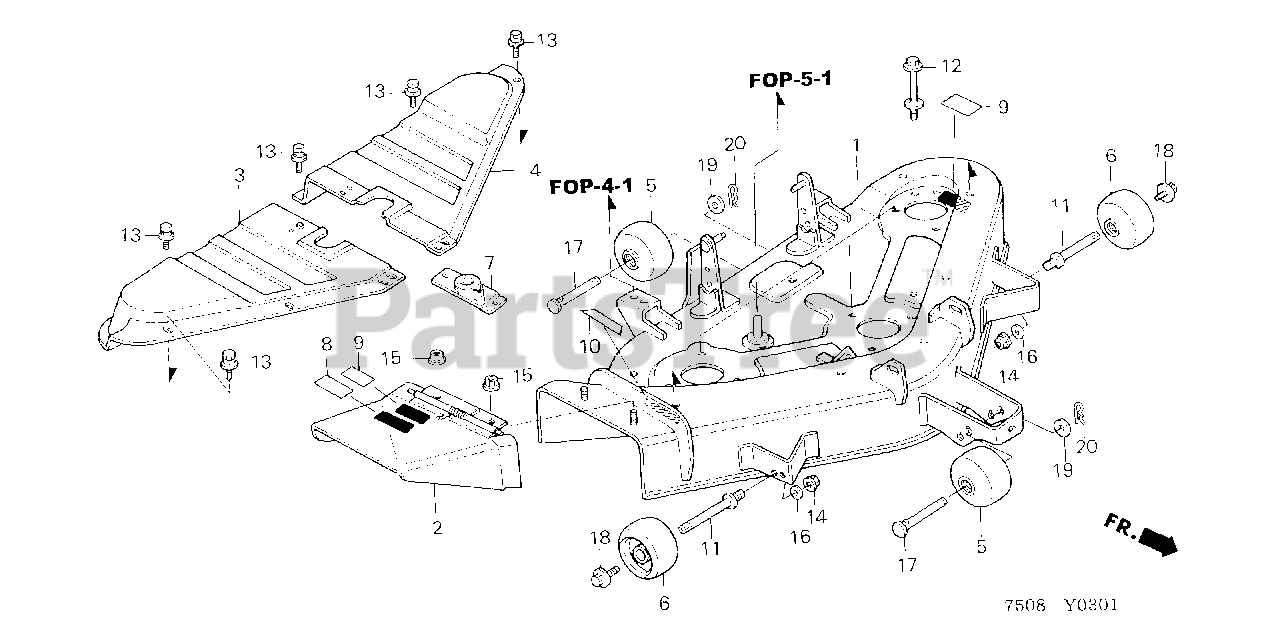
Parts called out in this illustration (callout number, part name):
1	HOUSING, CUTTER *NH190M* (VINTAGE GRAY METALLIC)
2	ADAPTER, DISCHARGE *NH190M* (VINTAGE GRAY METALLIC)
3	COVER, R. BELT *NH190M* (VINTAGE GRAY METALLIC) (NOT AVAILABLE)
4	COVER, L. BELT *NH190M* (VINTAGE GRAY METALLIC)
5	ROLLER, ANTI-SCALP
6	ROLLER, ANTI-SCALP
7	SEAL, BELT COVER *NH190M* (VINTAGE GRAY METALLIC)
8	LABEL B, WARNING (ENGLISH)
9	LABEL A, WARNING (ENGLISH)
10	MARK, CUT WIDTH (ENGLISH)
11	SHAFT, ANTI-SCALP ROLLER
12	BOLT, BELT STOPPER
13	BOLT-WASHER (6X16)
14	NUT, SELF-LOCK (12MM)
15	NUT, FLANGE (8MM)
16	WASHER, THRUST (12MM)
17	PIN, ANTI-SCALP ROLLER
18	BOLT-WASHER (8X12)
19	WASHER, FLAT (12MM)
20	PIN, LOCK (12MM)
